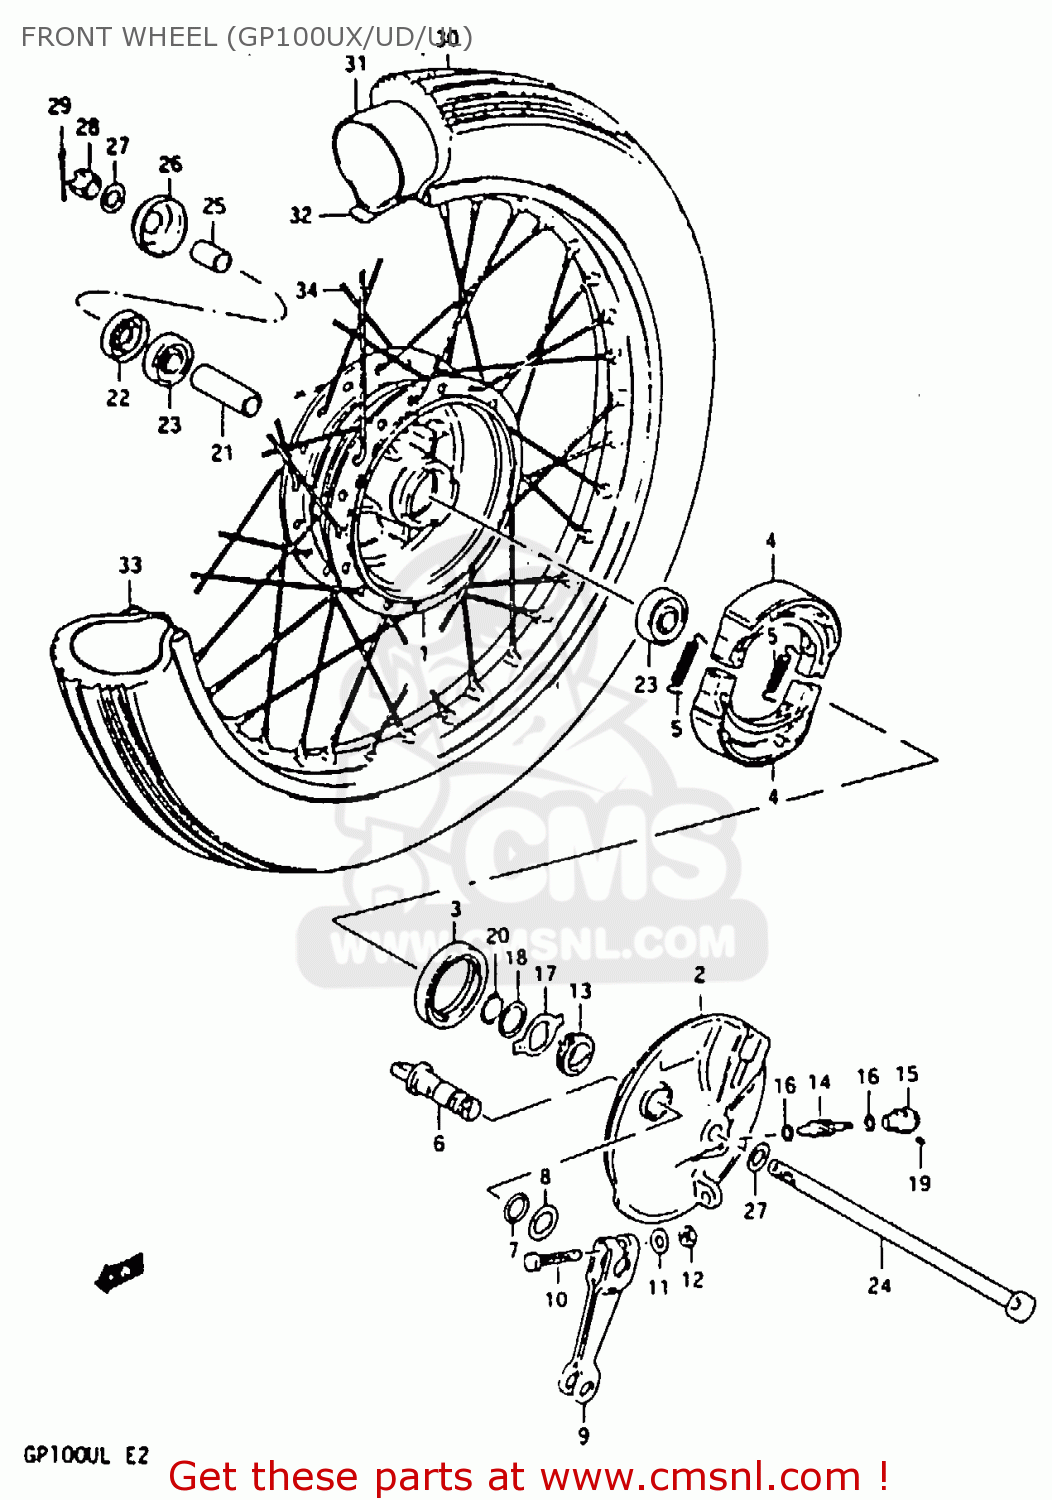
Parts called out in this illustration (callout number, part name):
1	HUB, FRONT
2	PANEL, FRONT HUB
3	SEAL,OIL(48X62X7)
4	SHOE,BRAKE
5	SPRING(L:34)
6	CAM,FRONT BRAKE
7	O-RING (D:2.4 ID:13.8)
8	WASHER (14.5X22X1.6)
9	LEVER,FR BRAKE CAM
10	BOLT(6X33)
11	WASHER
12	NUT 6MM
13	GEAR,SPEEDOMETER(NT:26)
14	PINION,SPEEDOMETER
15	BUSHING,SPEEDOMETER PINION
16	WASHER (5.1X9X0.4)
17	DRIVER,SPEEDOMETER GEAR
18	WASHER(18.5X24X1)
19	SCREW
20	CIRCLIP
21	SPACER(12.6X19X47)
22	OIL SEAL(17X38X5)
23	BEARING
24	AXLE,FRONT
25	SPACER, RH
26	COVER
27	WASHER
28	NUT
29	PIN 20X20
30	TIRE,FR(2.50-18 40L NF2)
31	TUBE,INNER
32	PROTECTOR,WHEEL,INNER
33	RIM,WHEEL(1.40X18)
34	SPOKE SET,FR
